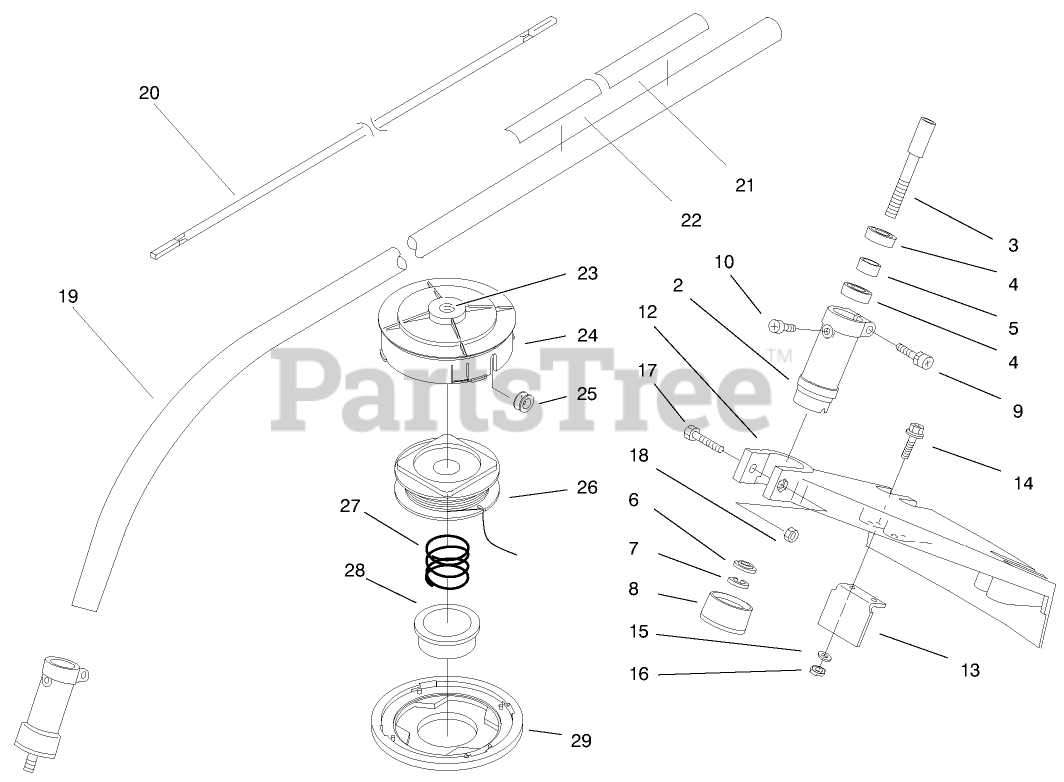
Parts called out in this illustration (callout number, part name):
2	BEARING HEAD
3	SHAFT
4	BEARING
5	SPACER
6	INNER CAP
7	WASHER - SPRING
8	OUTER CAP
9	SCREW
10	SCREW
12	SHIELD
13	STRING CUTTER
14	SCREW
15	WASHER - SPRING
16	NUT M5
17	SCREW
19	Driveshaft Tube Asm (Incl. Ref. # 22)
20	DRIVE SHAFT-FLEXIBLE
21	DECAL - TORO
22	DECAL - CAUTION
23	BOLT (UA-1006)
24	HOUSING
25	EYELET
26	SPOOL W/LINE (LH)
27	SPRING
28	BUTTON
29	COVER (SN-348L)
